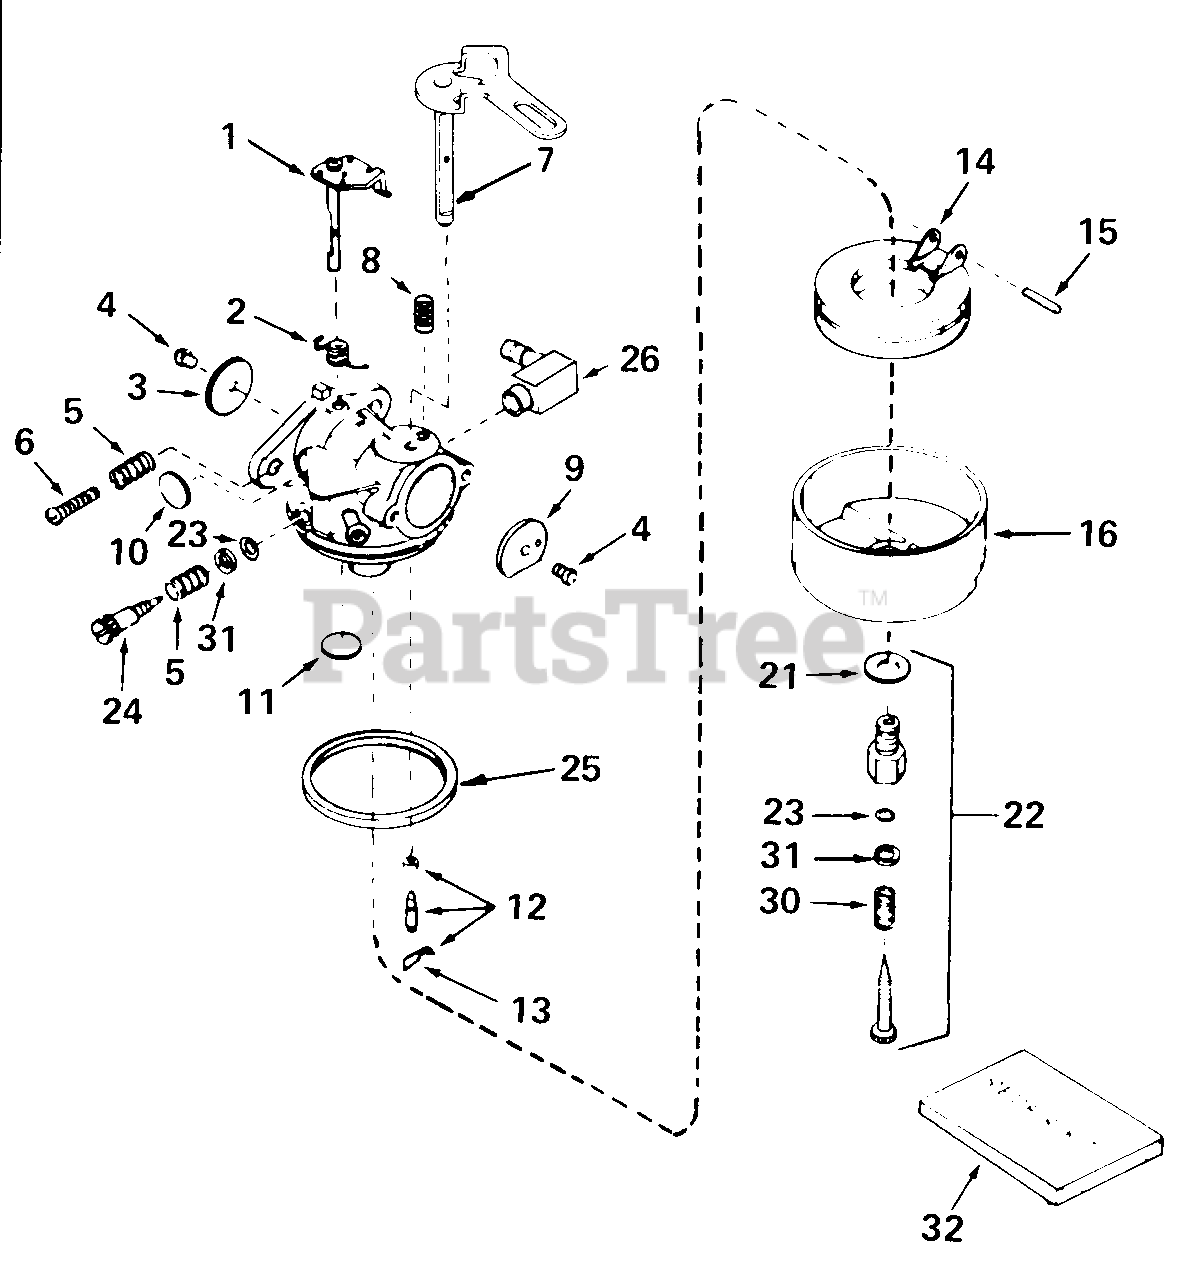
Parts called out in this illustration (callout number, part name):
1	Shaft & Lever Ass'y., Throttle
2	Spring, Throttle Return
3	Shutter, Throttle
4	Screw, 4-40 x 3/16
5	Spring, Idle Regulating Screw
6	Screw, Idle Regulating
7	Shaft & Lever Ass'y., Choke
8	Spring, Choke Stop
9	Shutter, Choke
10	Plug, Welch
11	Plug, Welch
12	Inlet Needle, Seat & Clip Ass'y.
13	Clip, Inlet Needle
14	Float, Carburetor
15	Shaft, Float
16	Bowl, Float
21	Gasket, Bowl-to-Body
22	Adjustment Screw Ass'y., Main
23	"O" Ring, Adjustment Screw
24	Screw, Idle Adjustment
25	Gasket, Bowl-to-Body
26	Fitting, Fuel Inlet
30	Spring, Main Adjustment Screw
31	Washer, Flat
32	Repair Kit
